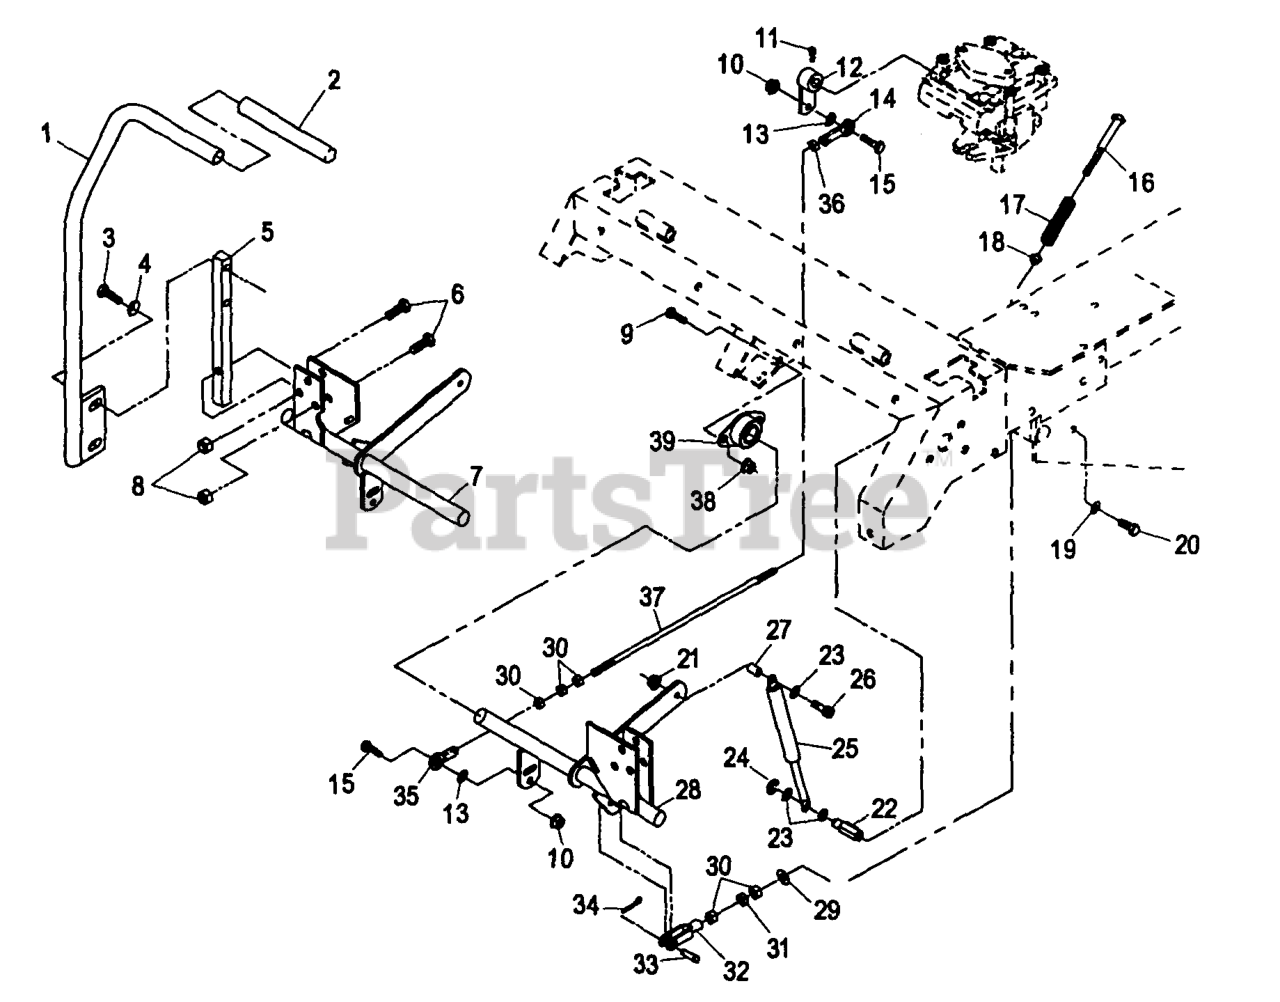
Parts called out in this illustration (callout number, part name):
1	ASM,LEVER/GRIP RH
2	GRIP-CONTROL, MOTION
5	ARM-CONTROL, SHAFT
11	SCREW-SET
14	BALLJOINT-LH
16	BOLT-RETURN, NEUTRAL
17	SPRING-RETURN, NEUTRAL
18	BUSHING-FLANGED
19	WASHER-SPRING
26	SCREW-HSH
32	YOKE-ADJUSTABLE
33	PIN-CLEVIS
35	BALLJOINT-RH
39	BEARING-FLANGE, SIDE
